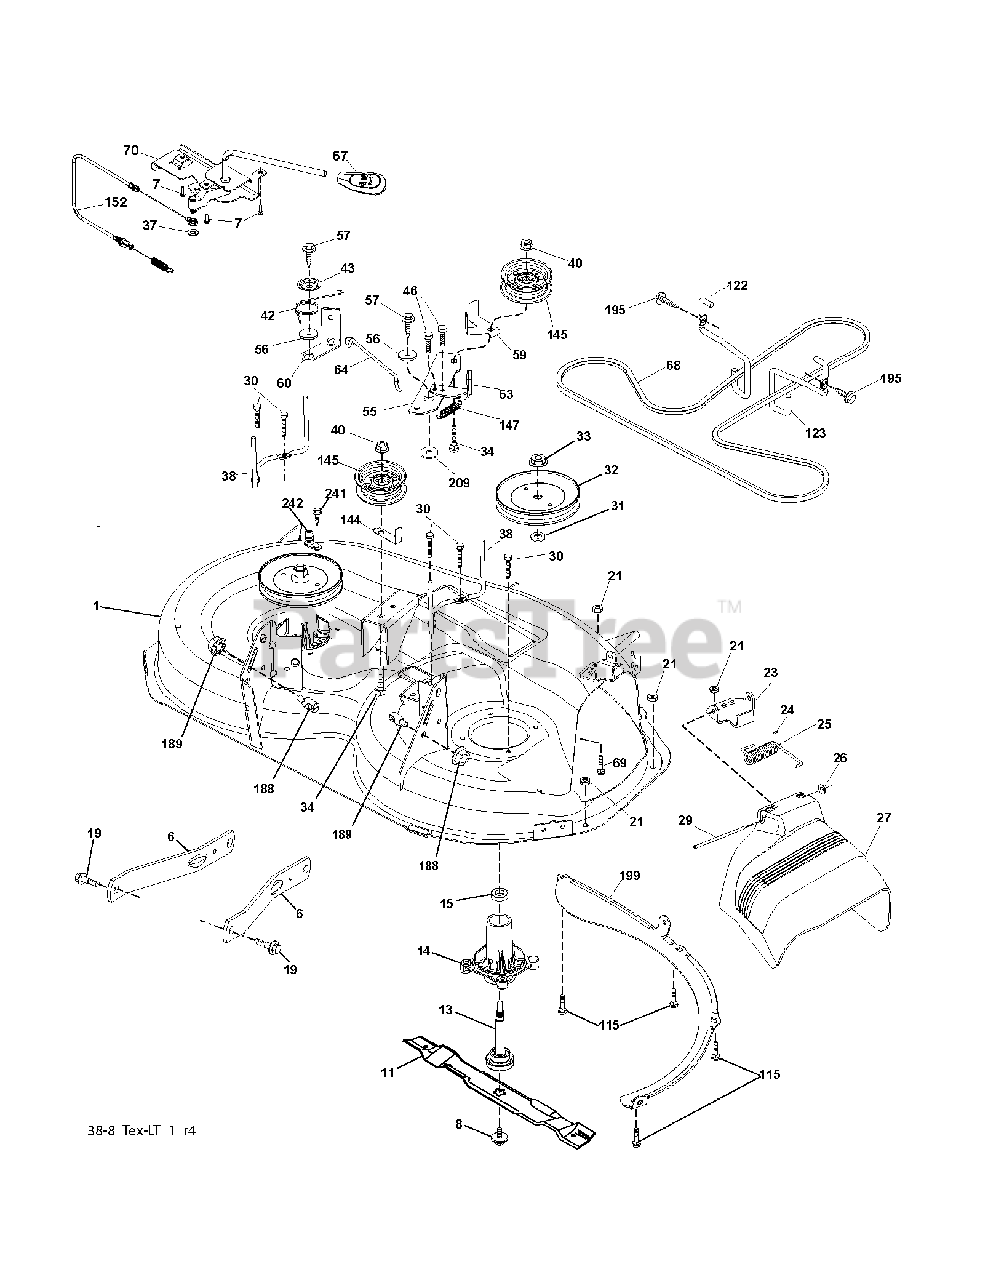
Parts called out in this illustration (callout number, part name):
1	DECK.WELD.38.NGW.TX.W/HOL.GREY
6	ARM.SUSPENSION.MOWER.R
7	SCREW.#10 X 0.750.BOS
8	BOLT.WASHER.ASM.7/16-2
11	BLADE.HI.LIFT.38"
13	SHAFT.ASM.MDRL.N/GREASE.38
14	HOUSING.MANDREL.4PT.
19	BOLT.SHOULDER
21	LOCKNUT
23	BRKT.DEFLECTOR.38"2005+
24	CAP-SLEEVE LT
25	SPRING.TORSION.DEFLECT
26	NUT PUSH M
27	SHIELD, DEFLECTOR
29	ROD.HINGE
30	SCREW, WASHER HEAD
31	WASHER.SPACER.MANDREL
32	PULLEY.MANDREL.5.0.PD.38"
33	NUT.FLANGE.LOCK.TOP
34	BOLT.3/8-16X1.50
37	WASHER
38	KEEPER BELT LH MANDREL
40	NUT LOCK FLG 3/8-16 UNC
42	SPRING.TORSION.BRAKE
43	SRPING.TORSION.RETAINE
46	SCREW.1/4-20X5/8
56	SPACER.RETAINER
57	SCREW 3/8-16X1
59	GUARD, BELT
60	ARM BRAKE MOWER RH 38"
63	RP ARM.BRAKE.MOWER.38"LH.TEX
64	LINK BRAKE
67	HANDLE.CLUTCH.CABLE.LT
69	BOLT
70	CLUTCH.ASM.MANUAL.LT.PRED
115	BOLT
122	KEEPER BELT ENGINE LH
123	KEEPER BELT RH
144	KEEPER BELT
145	PULLEY.IDLER.48"PRIMARY
147	SPRING RETURN
152	CABLE.CLUTCH.MANUAL.
188	STUD.FASTNER.W/ANTI-ROTATE
189	NUT LOCK HEX FLANGE 5/16-18
195	SCREW, 3/8-16X3/4
199	BAFFLE.VORTEX.FRONT.38"
209	WASHER 12/32X2X10GA
241	SCREW.TT.#10-32X.5.3/8.FLANGE
242	PORT.WASHOUT
